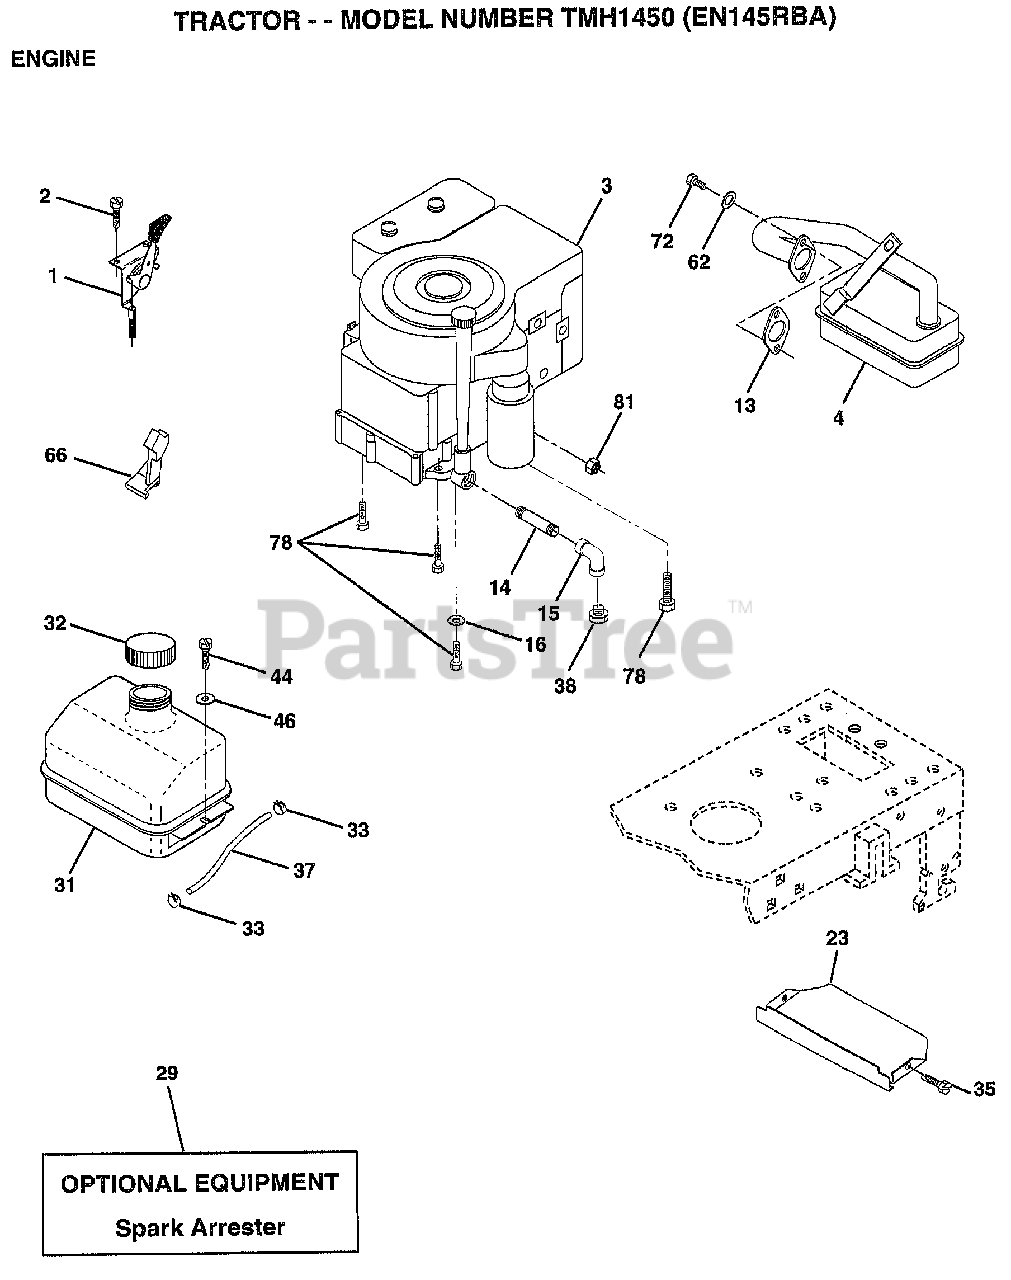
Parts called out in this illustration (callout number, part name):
1	CONTROL.THTL.23.5
2	SCREW LT
4	MUFFLER
14	PIPE NIPPLE
15	ELBOW
16	LOCKWASHER
23	SHIELD.BRN/DBR.GD
31	TANK.FUEL.LT.
32	CAP ASM FUEL
33	HOSE CLAMP
35	SCREW
37	LINE FUEL
44	SCREW HEX CRT
46	WASHER
62	LOCKWASHER
66	"STOP,DASH THROTT"
72	SCREW
78	SCREW
81	NUT
